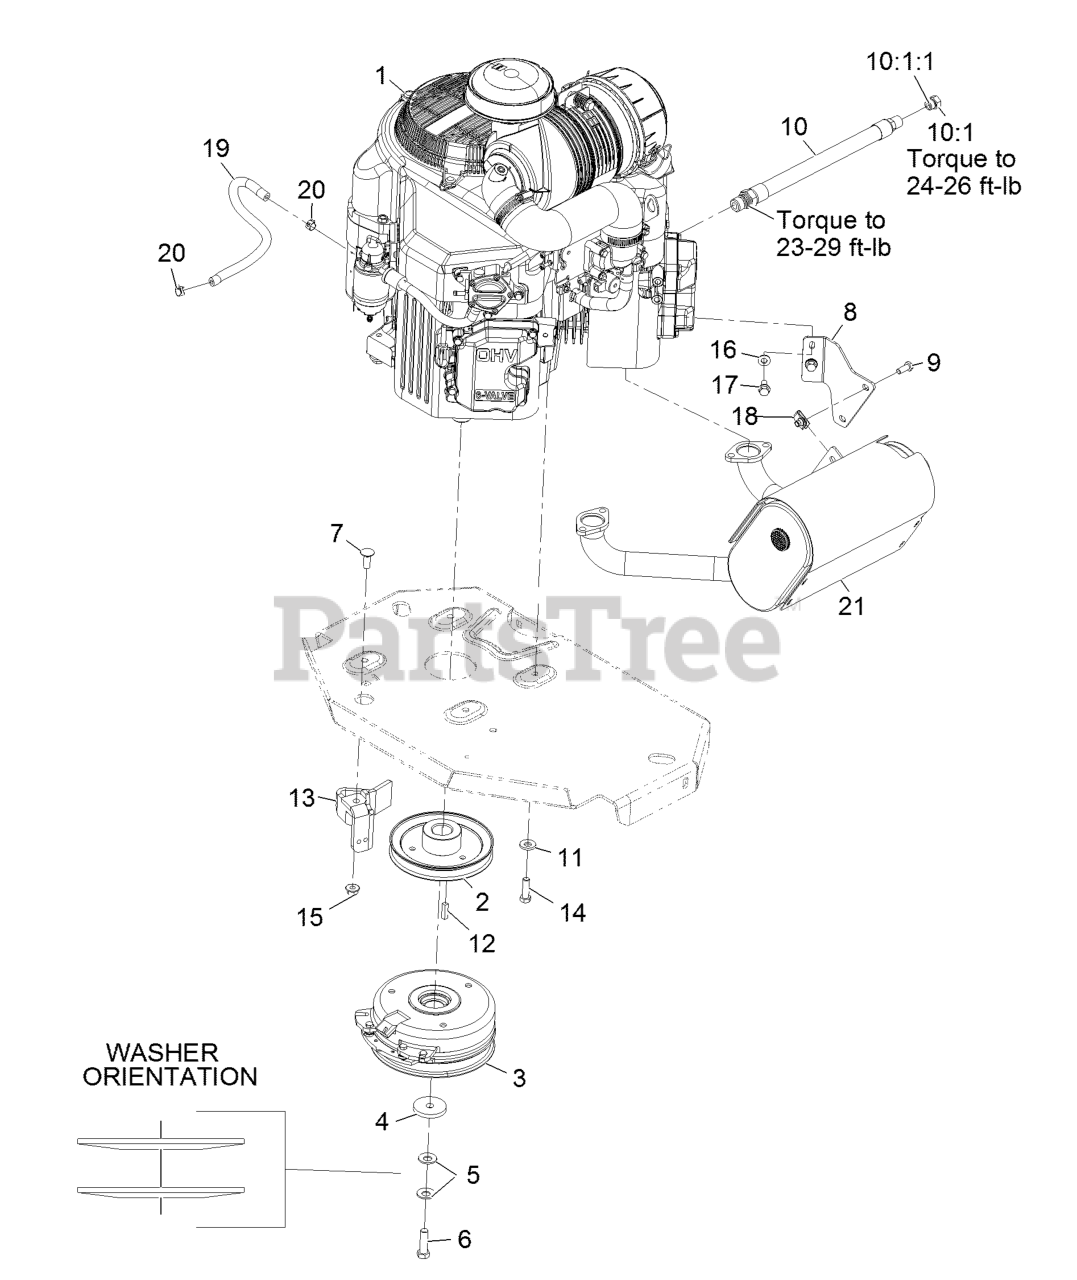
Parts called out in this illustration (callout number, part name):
2	SHEAVE
4	WASHER-CLUTCH
5	WASHER-SPRING
6	SCREW-HH 7/16-20 X 1 1/2 W/LOCTITE
7	SCREW-CARR
8	BRACKET-MUFFLER
9	SCREW-HH
10	ENGINE OIL DRAIN HOSE ASM
10:1	PLUG-HH
10:1:1	O-RING
11	WASHER-BELLEVILLE
13	CLUTCH-ANCHOR
14	SCREW-HH
15	NUT-HF, NI
16	WASHER-SPRING
17	SCREW-HHF
19	HOSE-FUEL
20	CLAMP-HOSE
21	MUFFLER
